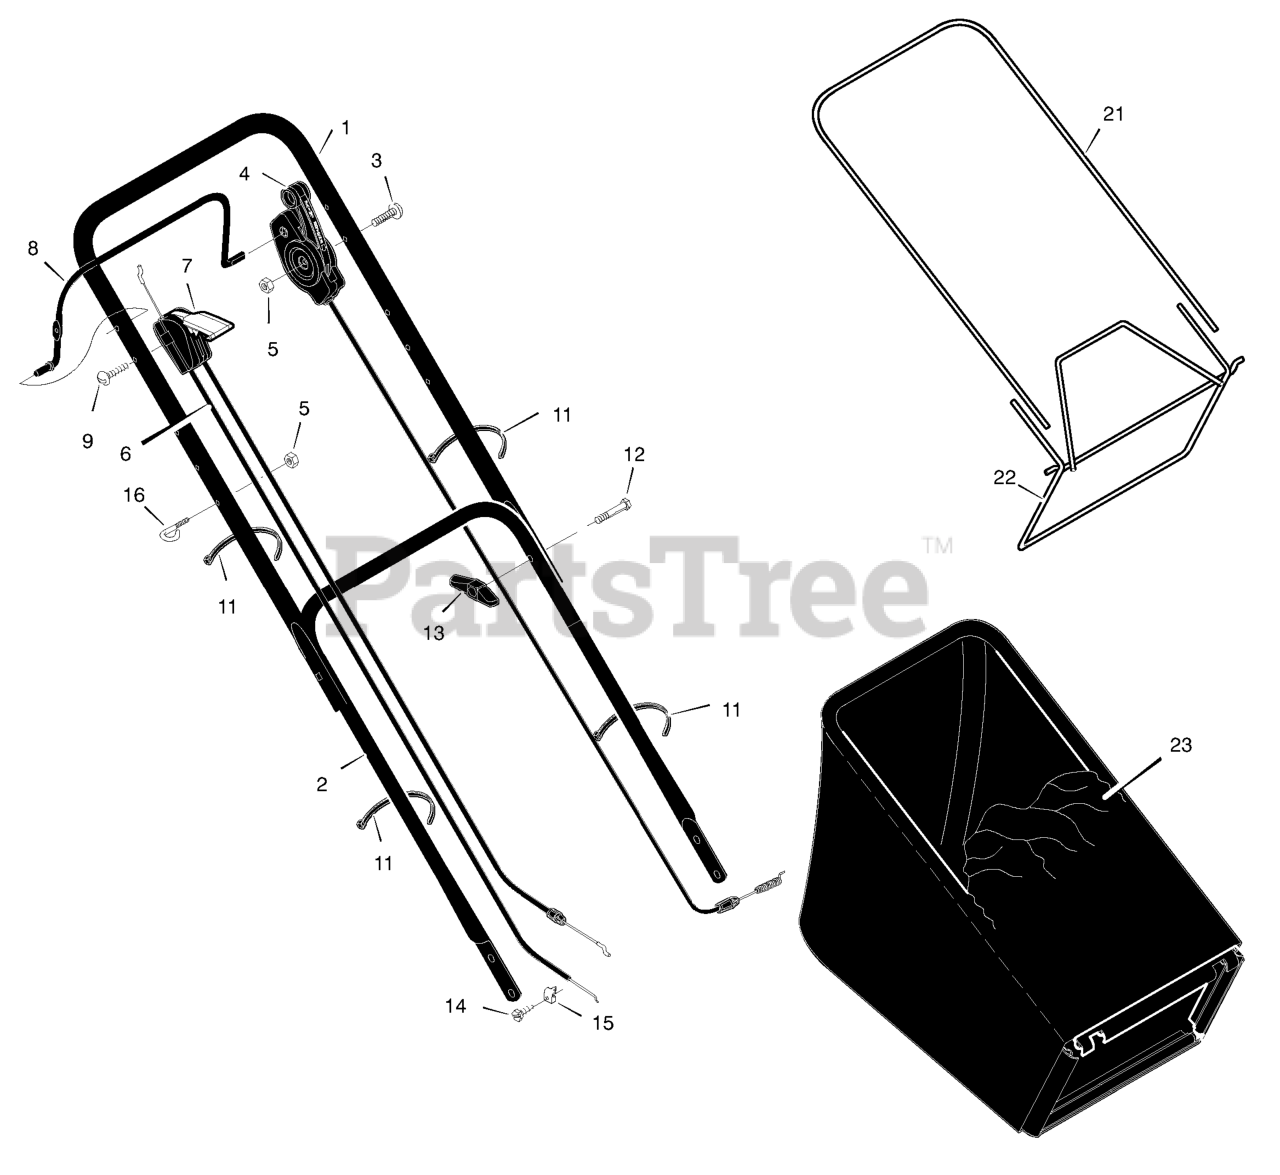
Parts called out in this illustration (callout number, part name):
1	Handle, Upper (Gray)
2	Handle, Lower (Gray)
4	Control, Drive
5	Locknut
6	Cable, Stop
7	Throttle Control
8	Engine Stop Lever
11	Fastener, Cable
13	Knob
16	GUIDE, ROPE
21	Frame, Top
22	Frame Assembly
23	Bag, Cloth
